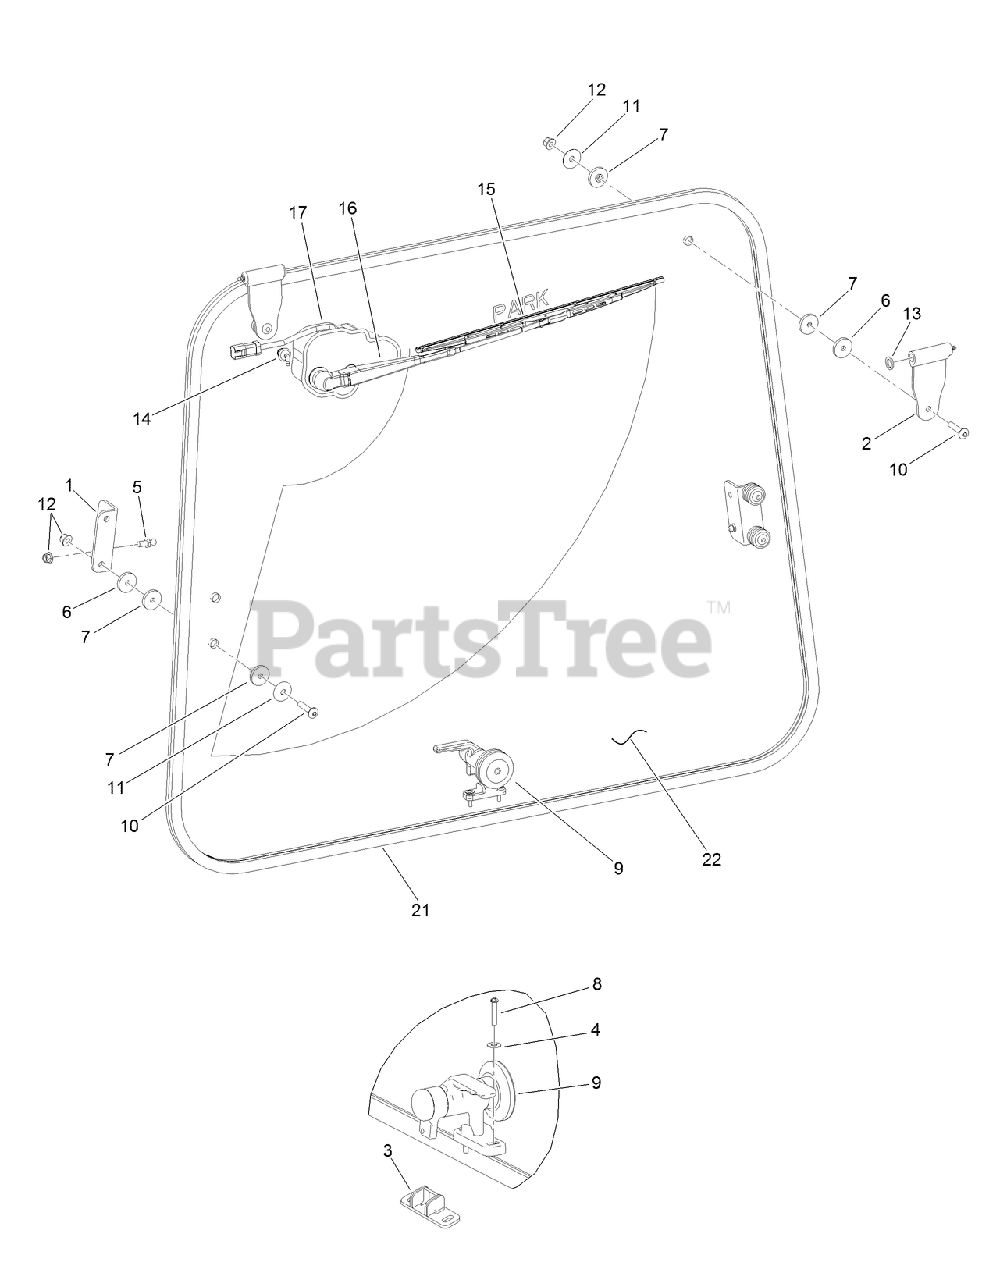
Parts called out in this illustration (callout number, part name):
1	MOUNT-GAS SPRING, REAR
2	HINGE-FEMALE
3	LOCK-WINDOW
4	WASHER-FLAT
5	STUD-BALL, GAS SPRING
6	WASHER-RUBBER
7	WASHER-SHOULDER, GLASS MOUNT
9	HANDLE-SELECTOR, LONG
11	WASHER-FENDER
12	NUT-HEX
13	WASHER-HINGE, BRASS
14	FITTING-HOSE, WIPER
15	BLADE-WIPER
16	WIPER-ARM, WET
17	MOTOR-WIPER
21	SEAL-TRIM
22	GLASS-WINDOW, REAR
